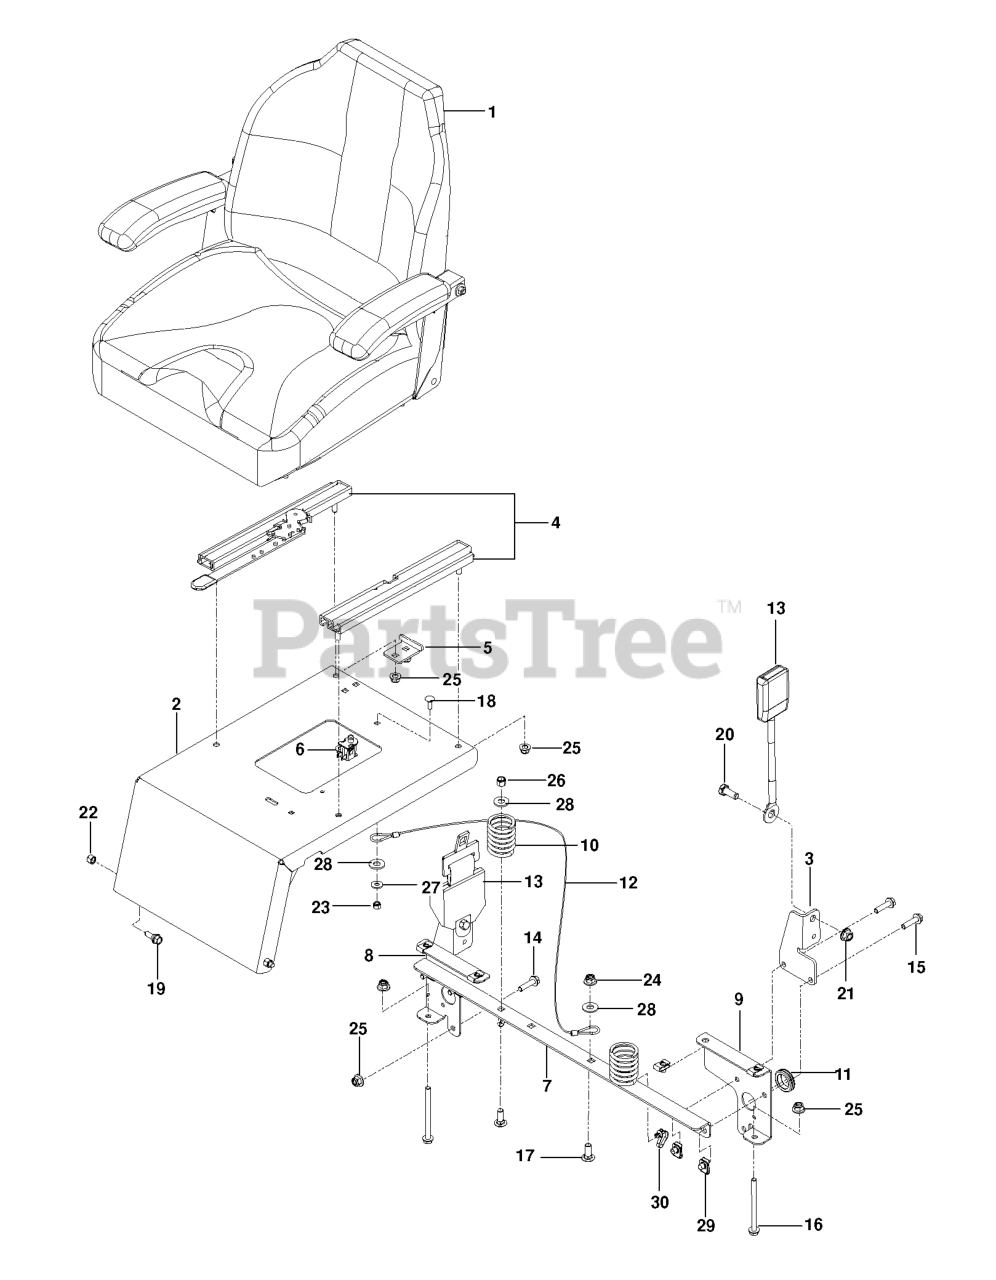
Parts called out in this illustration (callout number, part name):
1	SEAT.907.VINYL.HUSQVARNA
2	KIT.SEAT.MOUNT.W/DECAL
3	MOUNT.SEAT.BELT.BLACK
4	4"SINGLE LOCK TRACK SET W/HDWR
5	STOP, SEAT - BLACK
6	SEAT SWITCH
7	SUPPORT.SEAT. BLK
8	SUPPORT.RT.BLK
9	SUPPORT.LT.BLK
10	SPRING, SEAT
11	RUBBER GROMMET
12	SEAT LANYARD
13	SEAT BELT, RETRACTABLE
14	HHFS 5/16-18 X 3/4
15	HHFS 5/16-18 X 1.25 TPBLT GD 5
16	HHFS 5/16-18 X 3 3/4
17	RHSNB 3/8C X 1
18	RHSNB 1/4C X 3/4
19	SB 5/16-18 HEX HD GD5, BLK ZN
20	SCREW 7/16-20 X 1 HHB GR5
21	NUT HEX 7/16F LOCK RP
22	NUT 5/16 NYLOC
23	NUT.1/4-20.HEX.NYLOC.ZD
24	NUT 3/8-16 HEX FLG NYLOC ZD
25	5/16-18 NYLOC FLANGE NUT
26	NUT 3/8-16 NYLOC
27	WASHER 1/4 FLAT
28	WASHER 3/8 FLAT
29	U-CLIP 5/16-18 NUT RETAINER
30	TIE WRAP, 8-3/8", W/CLIP
